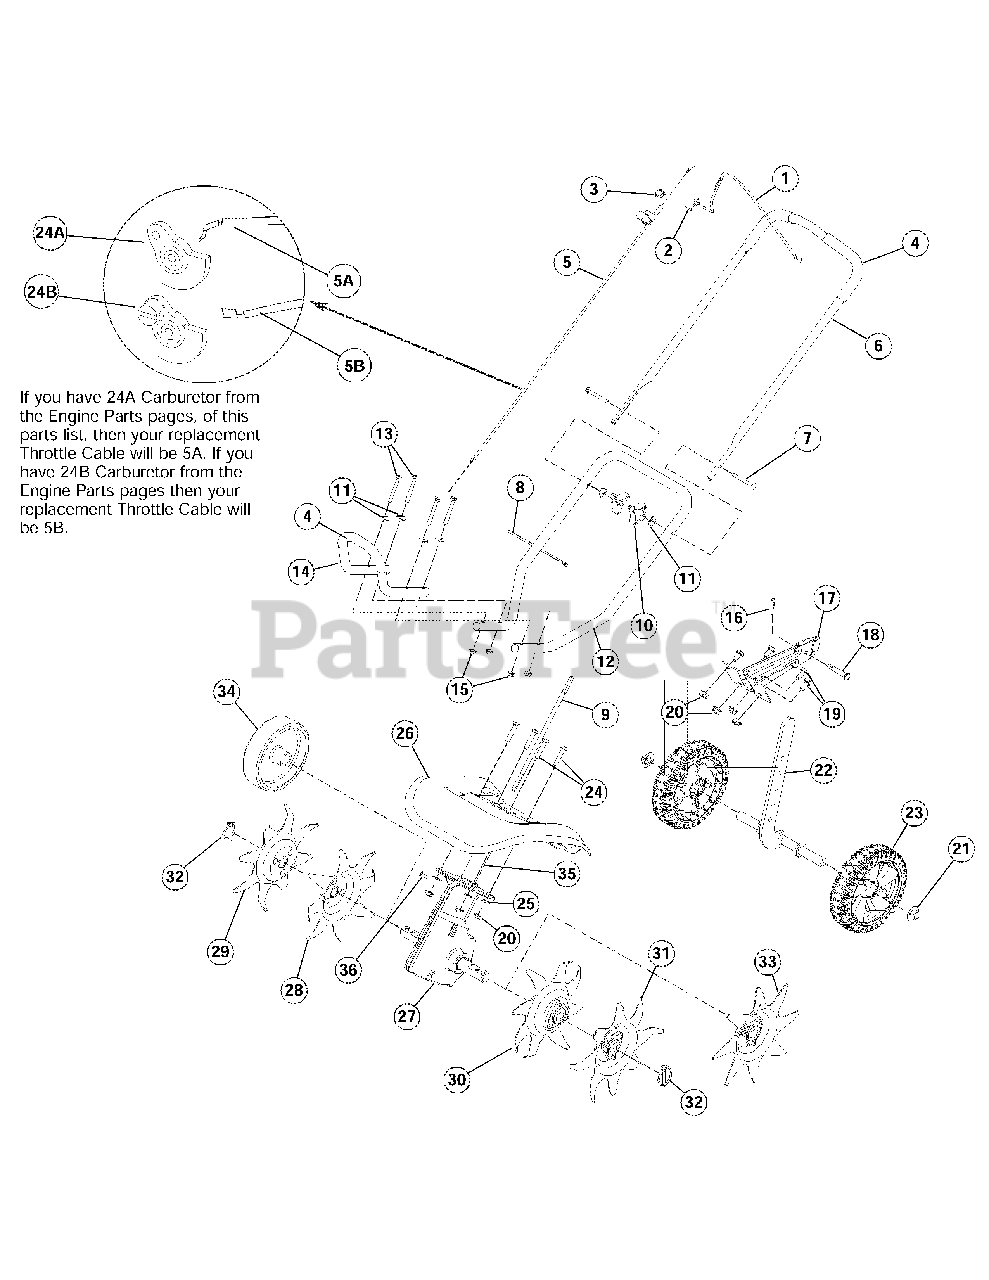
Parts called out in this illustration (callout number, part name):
1	Trottle Control
2	Torsion Spring
3	On/Off Switch
4	Foam Grip
5A	Throttle Cable
5B	Throttle Cable
6	Upper Handle
8	Cable Tie
9	Flex Shaft
11	Shoulder Washer
12	Lower Handle
13	Screw
14	Front Handle
15	Lock Nut
16	Cotter Pin
17	Tailpiece Bracket Assembly
18	Clevis Pin
19	Cap Screw
20	Lock Nut
21	Cap Push
22	Wheel Support Bracket Assembly
23	Wheel
24	Cap Screw
25	Washer
26	Tine Shield
27	Gear Box Assembly
28	Inner Tine (right side)
29	Outer Tine (right side)
30	Inner Tine (left side)
31	Outer Tine (left side)
32	Click Pin
33	Edger Tine
34	Edger Wheel
35	Drive Shaft Housing
36	Anti Rotation Screw
